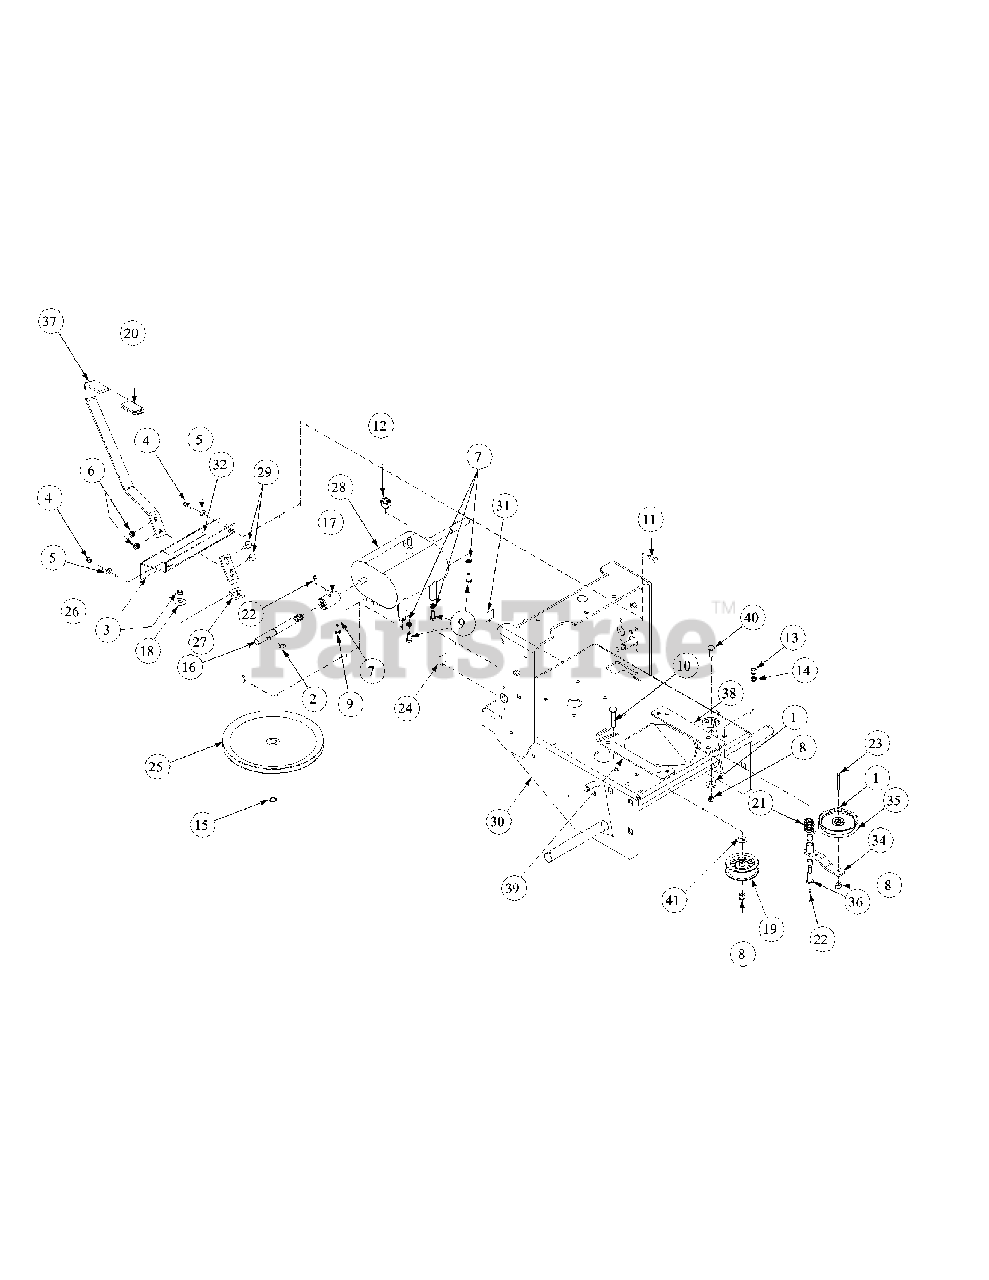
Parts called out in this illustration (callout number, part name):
1	Flat Washer, 3/8 Zinc
2	Woodruff Key, 3/16 x 3/4
3	Jam Nut, Insert Lock, 3/8-24
4	Lock Nut, Nylon Insert, 1/4-20
5	Flat Washer, 1/4 Zinc
6	Nut, 5/16-18 Nylock
7	Lock Washer, 5/16 Zinc
8	Lock Nut, Nylon Insert, 3/8-16
9	Hex Cap Screw, 5/16-18 x 3/4
10	Carriage Bolt, 3/8-16 x2
11	Carriage Bolt, 1/4-20 x .750
12	Switch, WB Transmission
13	Nut, 7/16-14
14	Lock Washer, 7/16
15	External Retainer Ring
16	Jackshaft w/ Heavy Spline
17	Coupling w/Heavy Spline
18	Bell Washer, .39 ID x .95 OD x .095
19	Flat Idler Pulley w/Adapter
20	Grip, .250 x 1 x 3-1/2, Yellow
21	Idler Torsion Spring
22	Grease Fitting, 1/4-28 x 3/16
23	Hex Cap Screw, 3/8-16 , 2.50
24	Decal "Made In America
25	Transmission Pulley
27	Shift Arm
28	Transmission, 5 Speed
29	Carriage Bolt, 5/16-18 x 1
30	Engine Deck Assembly
31	Label, Warning, Open Belt Drive
32	Label, Mower Instruction
34	Idler Assembly Bracket, w/Bearings
35	Idler Deck, Take-Up
36	Shoulder Bolt
38	Engine Spacer, LH
39	Engine Spacer,RH
40	Carriage Bolt, 3/8 -16 x 1
41	Idler Washer
